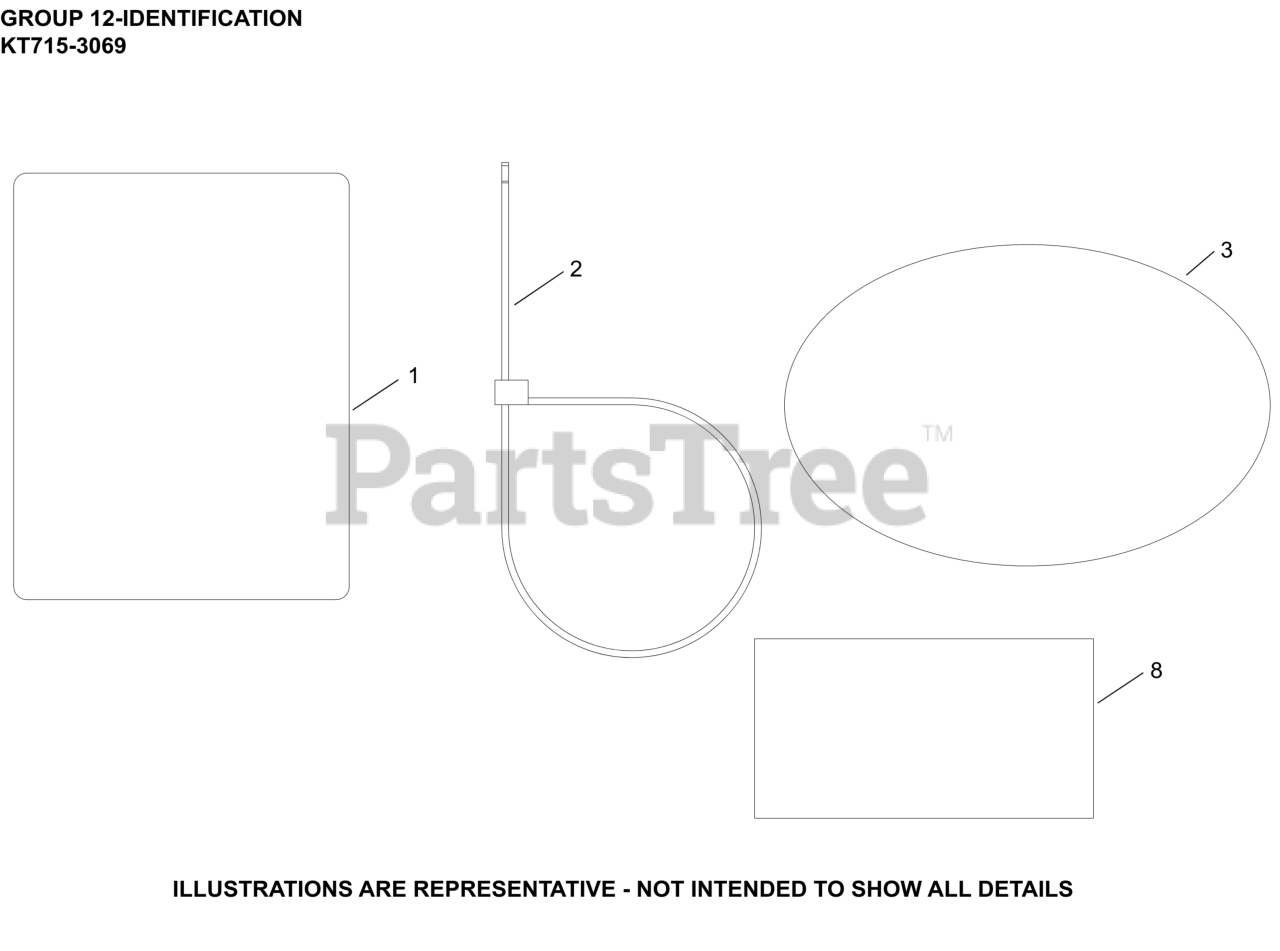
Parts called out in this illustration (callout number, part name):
1	LABEL, CLEAR LAMINATION
3	LABEL, 7000 SERIES (20HP, PRO)
8	DECAL, USA
